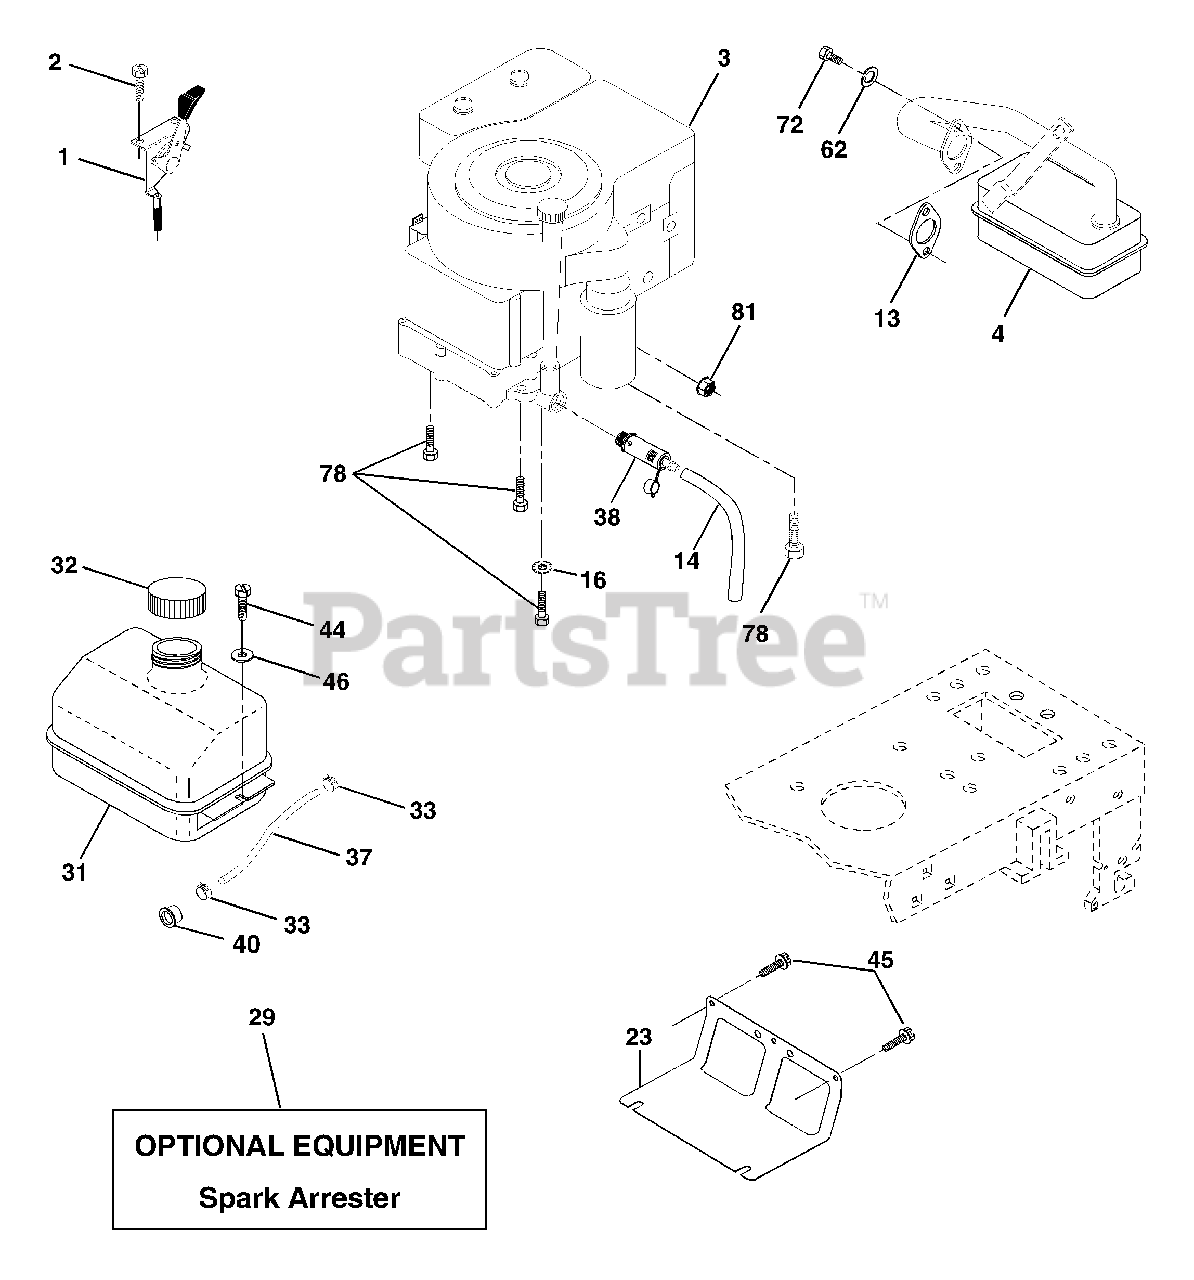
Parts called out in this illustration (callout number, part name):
1	Control Throt /Ch Flag
2	Screw Hex Thd Cut 1/4-20x1/2
4	Muffler Exhaust B&S Lt
13	Gasket 1 313 Id Tin Plated
14	Tube Drain Oil
16	Washer Lock Ext Tooth 3/8
23	Shield Browning/Debris Guard
29	Arrestor Spark
31	Tank Fuel 1 25 Fr
32	Cap Asm Fuel W/sym Vented
33	Clamp Hose Blk
37	Line Fuel 20"
38	Plug Drain Oil
40	Bushing Snap Nyl Blk Fuel Line
44	Screw Hexwsh Thdrol 1/4-20x3/4
45	Screw Hex Wsh Thdrol 3/8-16
46	Washer 9/32 X 7/8 X 16ga
62	Washer Lock Hvy Hlcl Spr 5/16
72	Screw Hexhd Cap 5/16-18x3/4
78	Screw 3/8-16x1-1/4
81	Nut Keps Hex 1/4-20 Unc
